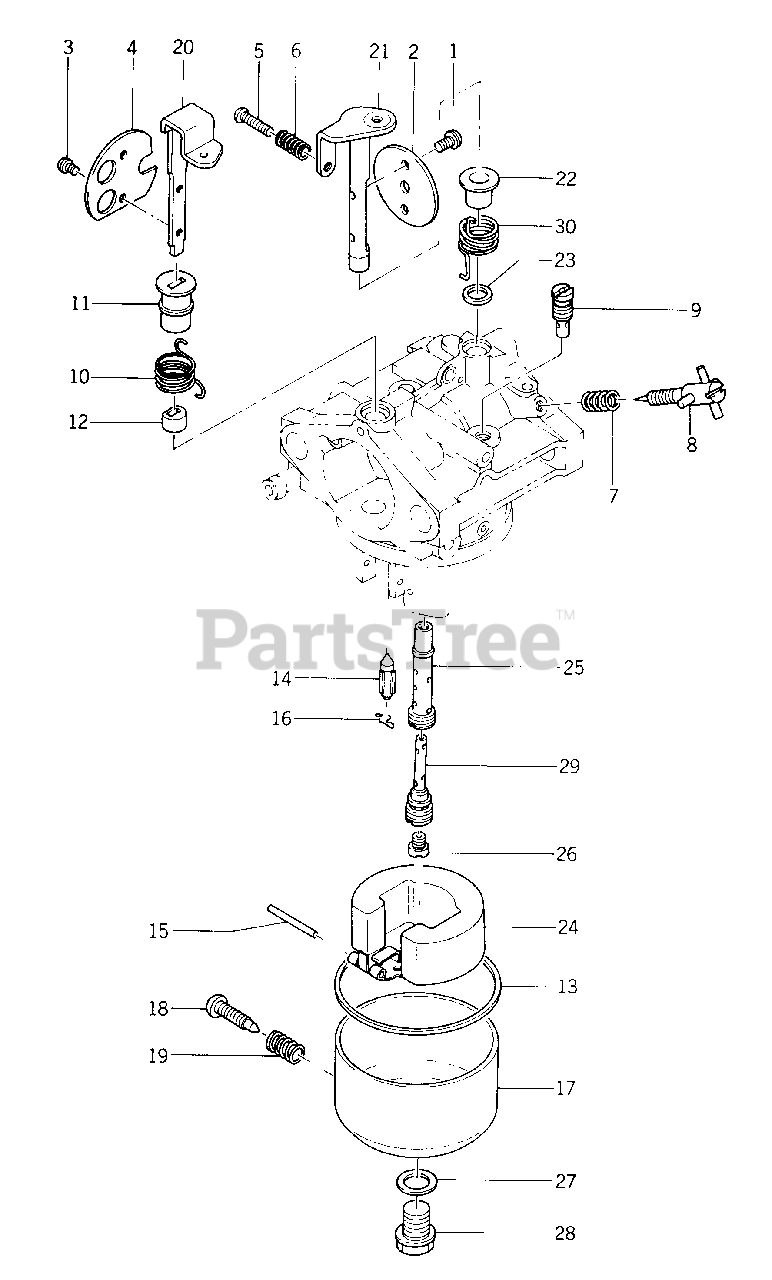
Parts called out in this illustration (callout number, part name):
1	SCREW
2	VALVE, throttle (#100)
3	UNSCREW
4	VALVE, choke
6	SPRING
7	SPRING
8	SCREW, adjuster
9	JET, pilot (#47. 5)
12	RING
13	GASKET
14	VALVE, needle
15	PIN, float
16	CLIP
17	FLOAT CHAMBER ASS'Y
18	SCREW, drain
19	SPRING
20	SHAFT, choke
21	SHAFT, throttle
23	SEAL
24	FLOAT
25	NOZZLE, main (#6A)
26	JET, main (#112.5)
27	WASHER
28	BOLT
29	HOLDER, main jet
